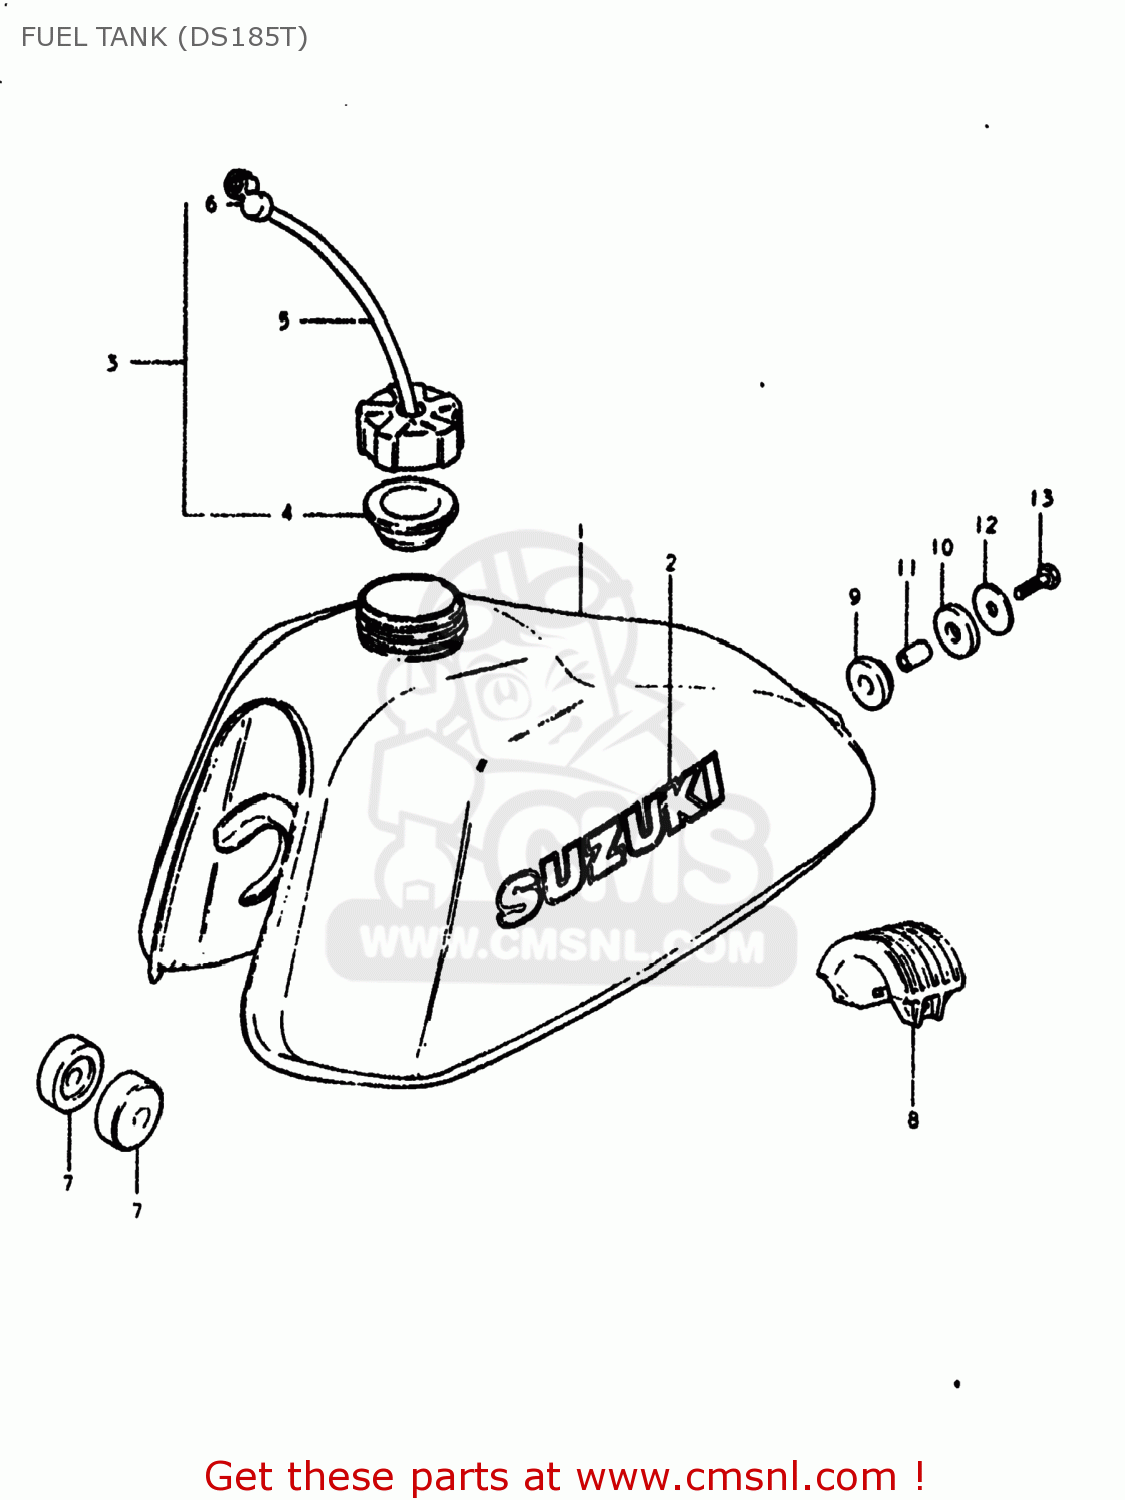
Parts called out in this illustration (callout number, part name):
1	TANK ASSEMBLY,FUEL
2	EMBLEM,FUEL TANK(WHITE)
3	CAP SET,FUEL TANK
4	GASKET,FUEL TANK CAP (NAS)
5	HOSE
6	CLAMP,FUEL TANK BREATHER HOSE
7	CUSHION
8	CUSHION,FUEL TANK
9	CUSHION
10	CUSHION
11	SPACER(8.5X12X19)
12	WASHER (8.5X29X1.6)
13	BOLT (8X30)
